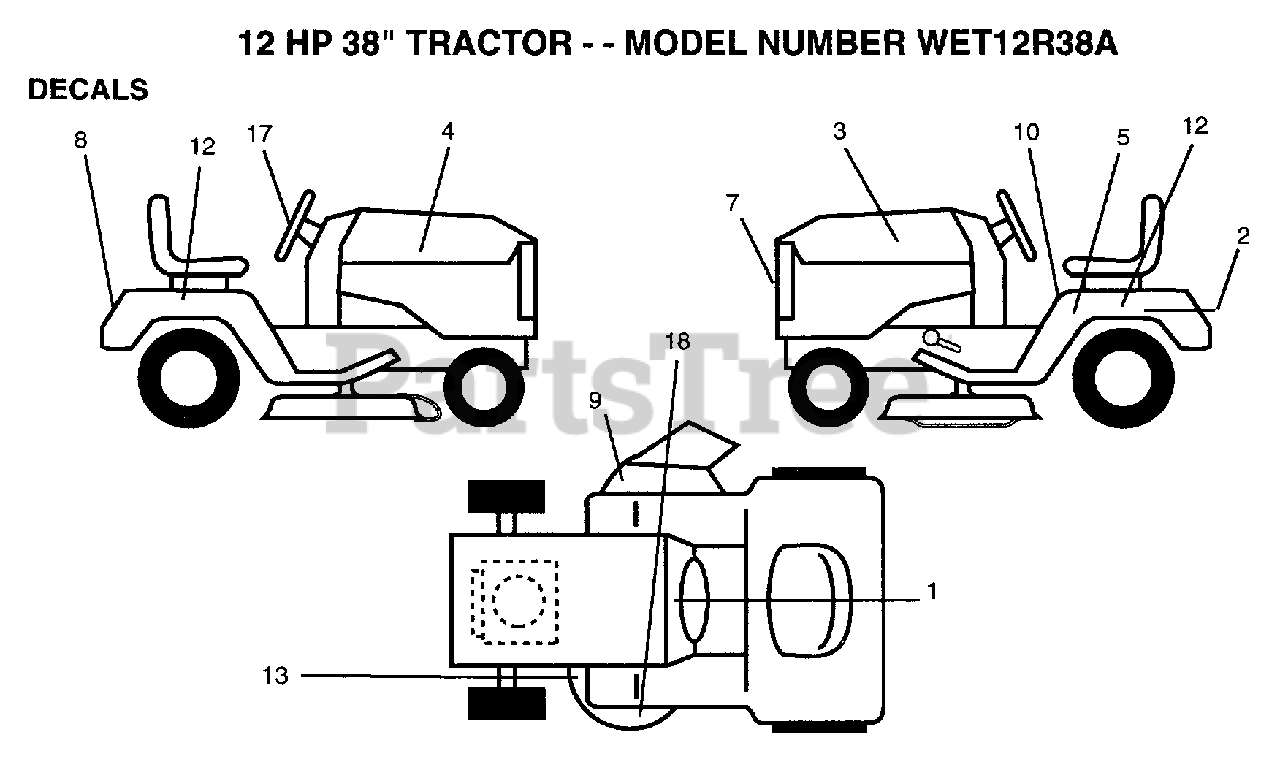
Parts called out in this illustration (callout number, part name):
2	DECAL
3	DECAL.HOOD.LH
4	DECAL.HOOD.RH
5	IND HGT DECK DECA
7	"DECAL,LIGHT BOX"
8	DECAL.FENDER
9	"DECAL, WARNING"
10	DECAL CAUTION
12	DECAL.FEND.QUICKS
13	DECAL
17	DECAL.WHL.STRG.
18	DECAL.MOWER
